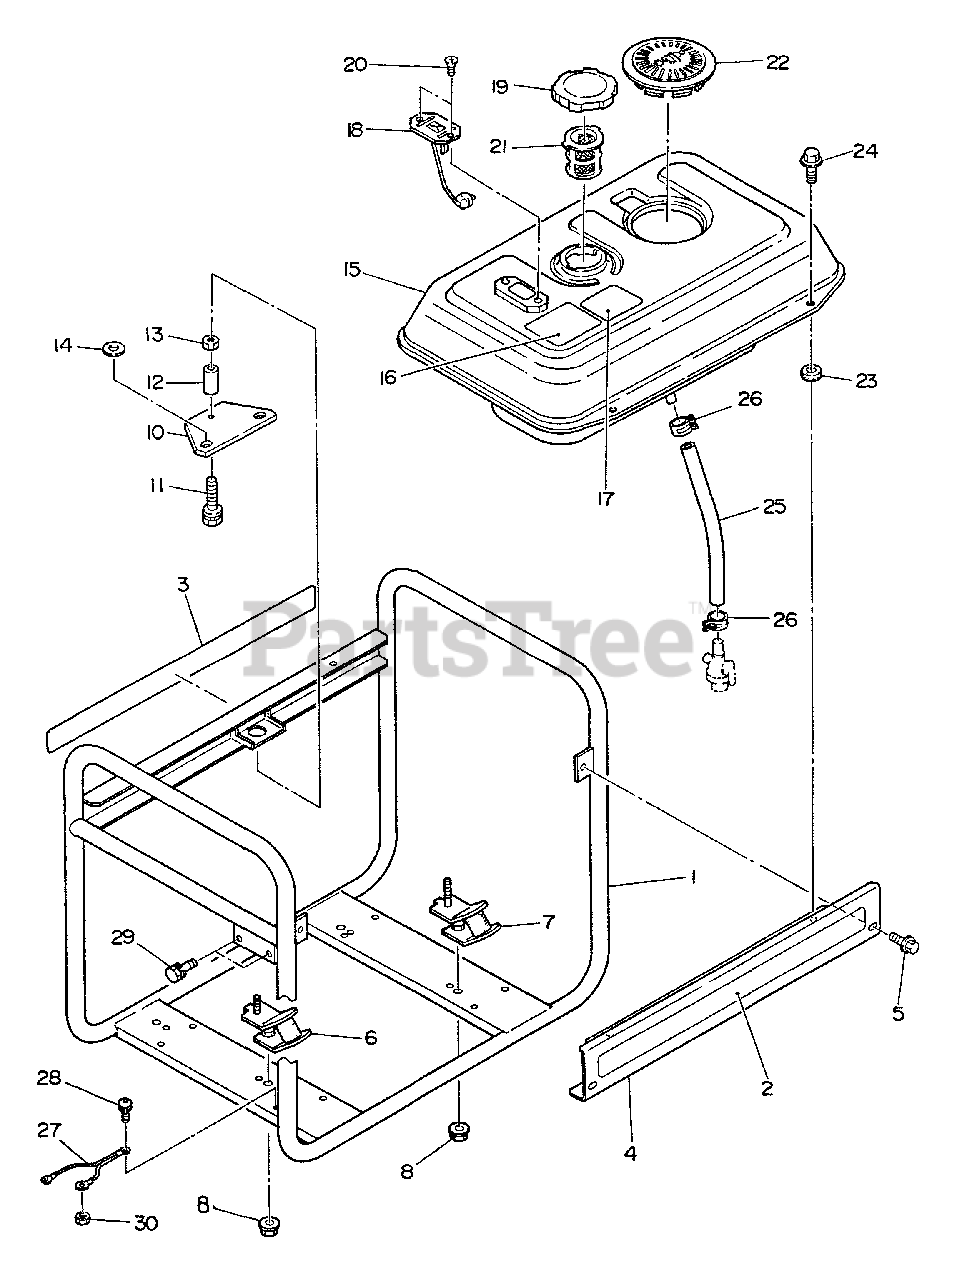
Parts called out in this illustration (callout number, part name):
1	PIPE FRAME, COMPL.
2	LABEL - MODEL EG-3501
3	LABEL - MODEL EG-3501
4	SIDE PLATE, COMPL.
5	BOLT - FLANGE
6	MOUNT, RUBBER
7	MOUNT, RUBBER
8	NUT, FLANGE
10	STOPPER PLATE
11	BOLT
12	SPACER
13	NUT
14	WASHER
15	FUEL TANK ASSY
16	LABEL - CAUTION -- OPERATION
17	LABEL - DANGER
18	LEVEL GAUGE, COMPL.
20	SCREW
21	FILTER, FUEL
22	PLUG COVER
23	RUBBER WASHER
24	BOLT, FLANGE
25	RUBBER PIPE (11.5×17.5×230 MM)
26	CLAMP, HOSE
27	LEAD - GROUND
28	SCREW
29	BOLT
30	NUT
